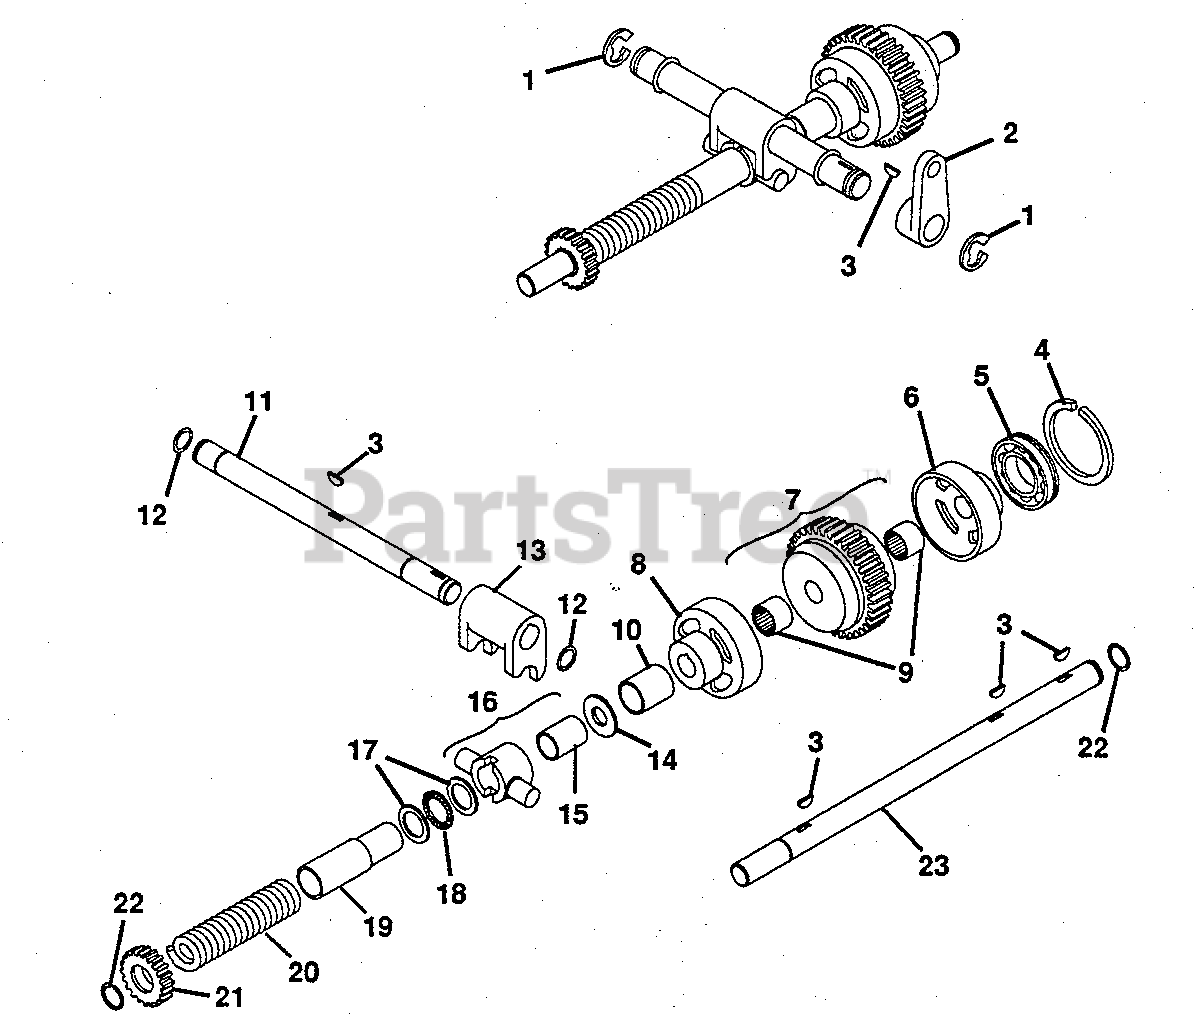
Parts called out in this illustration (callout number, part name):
1	E-RING, .750 SHAFT
2	LEVER, PTO
3	KEY, WOODRUFF .187X.750 HARD #9
4	RING, RETAINING 1.375 EATON 340-1
5	BEARING, BALL 1.378X2.440X.551
6	CUP, CLUTCH
7	ASSEMBLY, CLUTCH CONE BEARING
8	CUP, CLUTCH
9	BEARING, NEEDLE .750X1.00X.50
10	SPACER, PTO
11	SHAFT, PTO YOKE
12	O-RING, .625X.750X.060
13	YOKE, PTO
14	RACE, THRUST BEARING .752X1.240X.095
15	BUSHING
16	ASSEMBLY, SHIFTING COLLAR
17	BEARING, THRUST RACE 1.002X1.552X.093
18	BEARING, NEEDLE THRUST 1.002X1.552
19	THROW-OUT, PTO
20	SPRING, COMP. TYPE 5X1.50X200 RATE
21	GEAR, SPUR PTO 10 DP 22 TEETH X 1.200 STD.
22	RING, RETAINING .750 SHAFT
23	SHAFT, PTO CLUTCH
